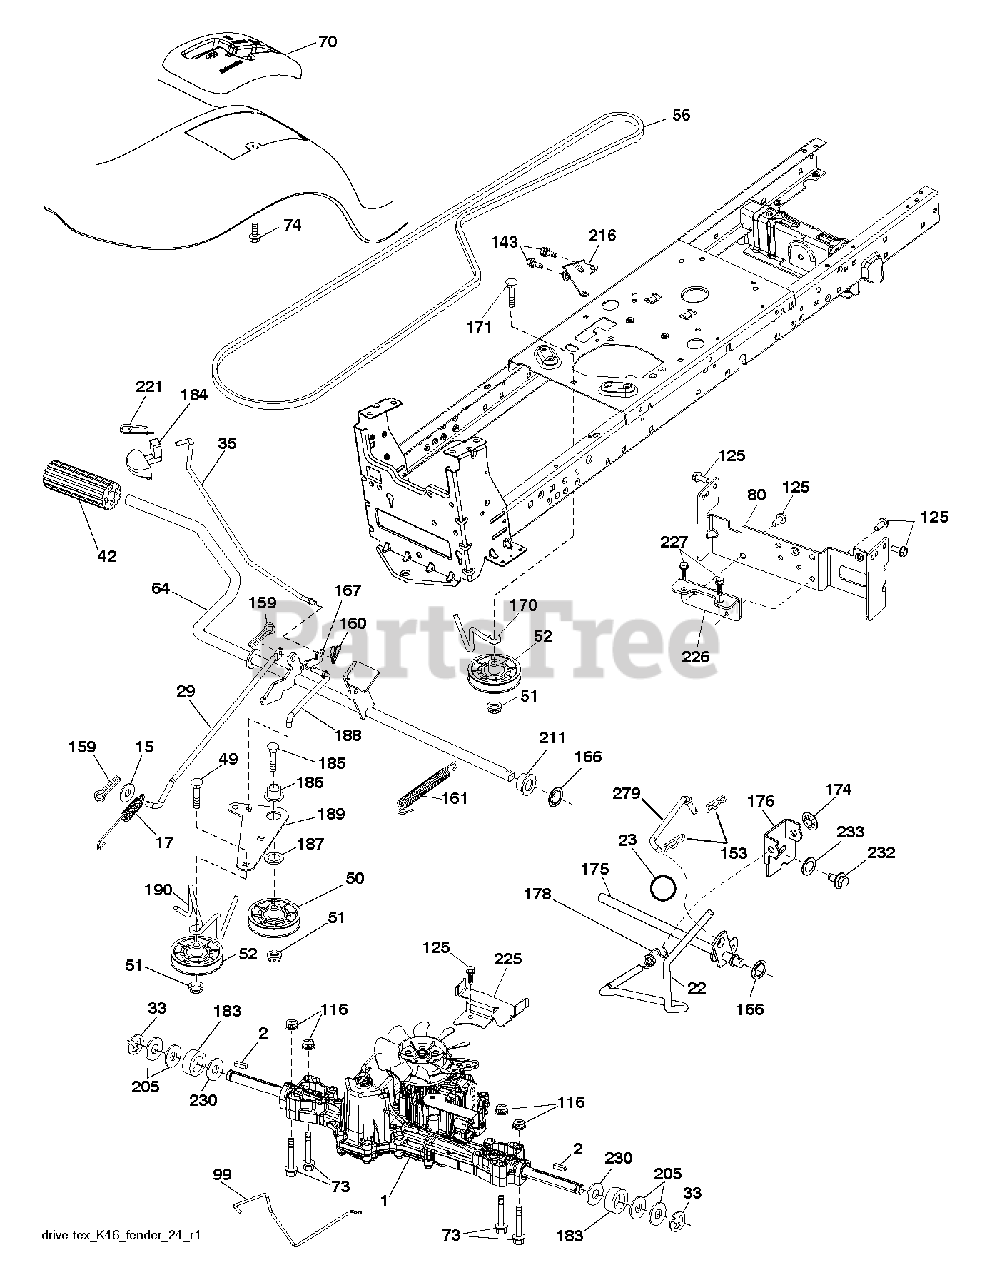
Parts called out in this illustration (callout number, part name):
2	SQUARE KEY
17	SPRING.BRAKE.K46.GREEN
22	ROD.SHIFT.FENDER.TLT.2006
23	KNOB.DELUXE.(PISTOL.GRIP).BLAC
29	ROD.BRAKE.K46
33	E-RING LT
35	ROD.BRAKE.PARKING.LT.T
49	BOLT
50	IDLER.FLAT.910.OFFSET
51	NUT LOCK FLG 3/8-16 UNC
52	IDLER.V-GROOVE.910.OFFSET
56	V-BELT.MOWER.92.40.42/K46
64	SHAFT.ASM.PEDAL.BRAKE.
70	CONSOLE.SHIFT.STL.HYD.BLACK
73	BOLT
74	SCREW.HI-LO.CONSOLE
80	STRAP.TORQUE.K46.K57R.TT
99	ROD.SPRING.BYPASS.K46.LT.Z
116	NUT LOCK HEX FLANGE 5/16-18
125	SCREW
143	SCREW LT
159	COTTER PIN
160	RETAINER CLIP
161	SPRING, RETURN LT
166	NUT.PUSH.625
167	LATCH.BRAKE.SPRING
170	KEEPER.V-IDLER.CENTER.
171	BOLT
174	NUT.PUSH.500.2006
175	SHAFT ASM SHIFT
176	ARM.CLEVIS.ROD.SHIFT
178	SPRING.SHIFT.GT2006
183	SPACER AXLE
184	HANDLE.PARKING.BRAKE.LTTEX.667
185	BOLT
186	SPACER.RETAINER
187	WASHER 12/32X2X10GA
188	LINK.CLUTCH.GROUND.DRIVE
189	BELLCRANK.GROUND.DRIVE.TEX.
190	KEEPER.BELLCRANK.DRIVE
211	BUSHING.SHAFT.BRAKE.HAND
216	BRACKET.PULLEY.IDLER.W/TEX
221	RETAINER.SPRING.CLIP.H
225	KEEPER.BELT.TRANSAXLE.K46
226	BRACKET.MOUNT.TORQUE.K46.TLT
227	Screw, Lt
230	WASHER.HARDENED
232	BOLT FIN HEX 7/16-14 X 1
233	WASHER SERRATED
279	LINK.SHIFT.T/A.K46.FEND.TX
